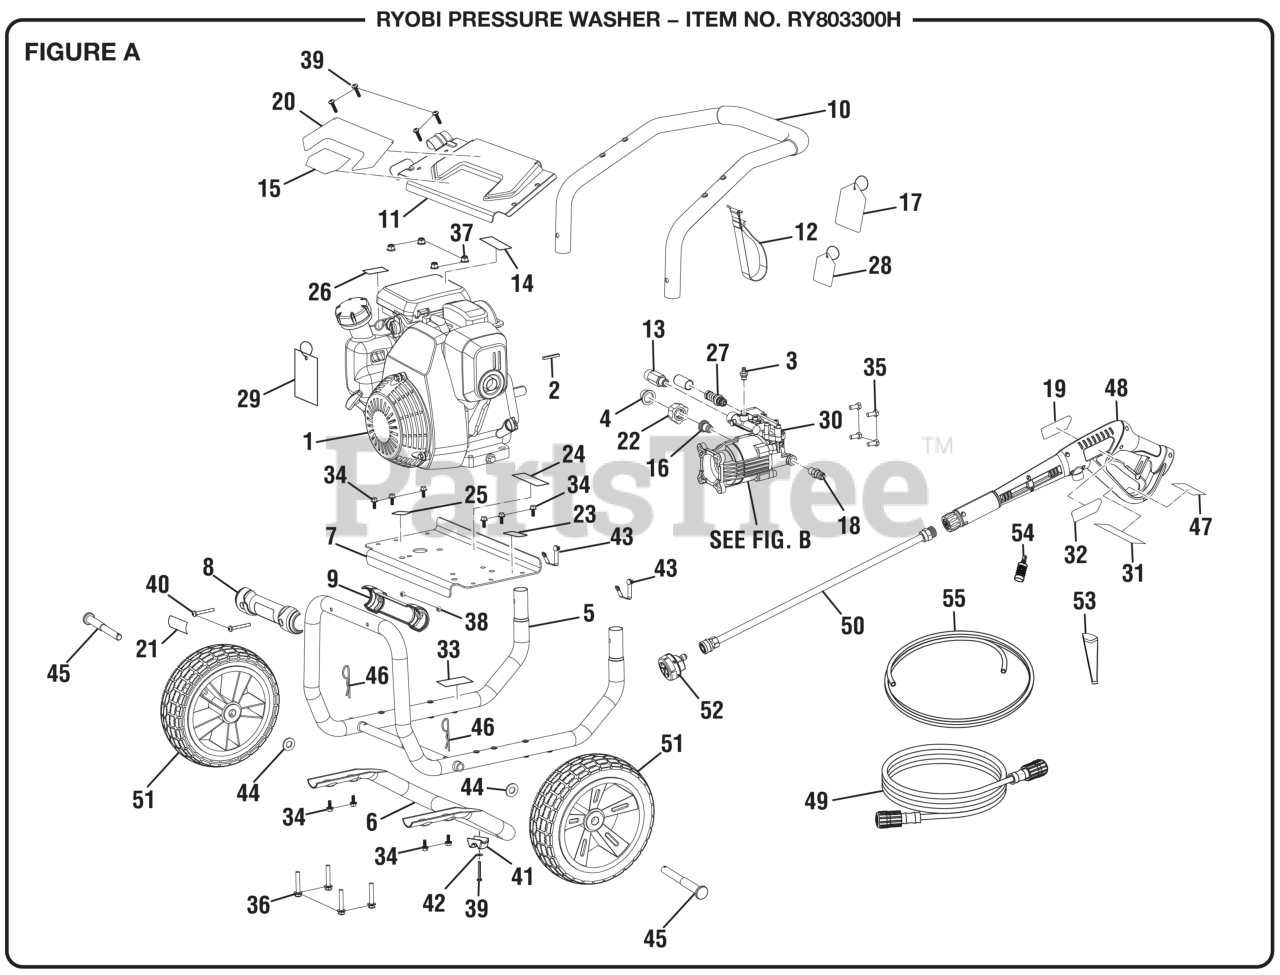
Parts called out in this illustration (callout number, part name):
2	Output Shaft Key (3/16 in. x 40 mm)
3	Detergent Injector Assembly
4	Filter Screen (Pump Inlet)
5	Main Frame Assembly
6	Rear Frame Assembly
7	ENGINE PLATE
8	Handle Grip (Front)
9	Handle Grip (Back)
10	Handle Assembly
11	Performance Panel
12	Hose Holder Strap
13	Outlet Tube
14	Hot Surface and
15	Performance Label
16	Inlet Filter Adapter/Brass Insert
17	Quick Start Hangtag
18	Thermal Release Valve.
19	LABEL, TRIGGER HANDLE LOGO
20	Logo Label (Performance Panel)
21	Throttle Label
22	Inlet Filter Connector
23	Oil Fill Location Label
24	Combustion Warning Label
25	Danger Label
26	No E85 Label
27	Unloader Valve Assembly
28	5- In- 1 Nozzle Hangtag
29	Danger Hangtag
31	LABEL, TRIGGER HANDLE RATING, EN FR SP
32	Trigger Handle Warning Label (English)
33	Warning Label
34	Flange Bolt (M6 x 1 x 16 mm, Hex Hd.)
35	Bolt (5/16-24 x 3/4 in., Hex Hd.)
36	Bolt (M8 x 1.25 x 40 mm, Flange Hd.)
37	Lock Nut (M8 x 1.25 mm, Flange)
38	Lock Nut (M6 x 1)
39	Screw (M6 x 1.25in., T30 Torx Pan Hd.)
40	Screw (M6 x 1 x 48 mm, T30 Torx Pan Hd.)
41	Rubber Foot
42	Washer (1/4 in.)
43	Lock Button w/Spring Clip.
44	Washer (1/2 in.)
46	Hitch Pin
47	Label (Trigger Handle Warning, French & Spanish)
48	Trigger Handle Assembly
49	HOSE, M22, 35', 1/4"", GREEN
50	Extension Wand
52	5-in-1 change over nozzle
54	Detergent Injection Filter
55	Detergent Injection Tube
